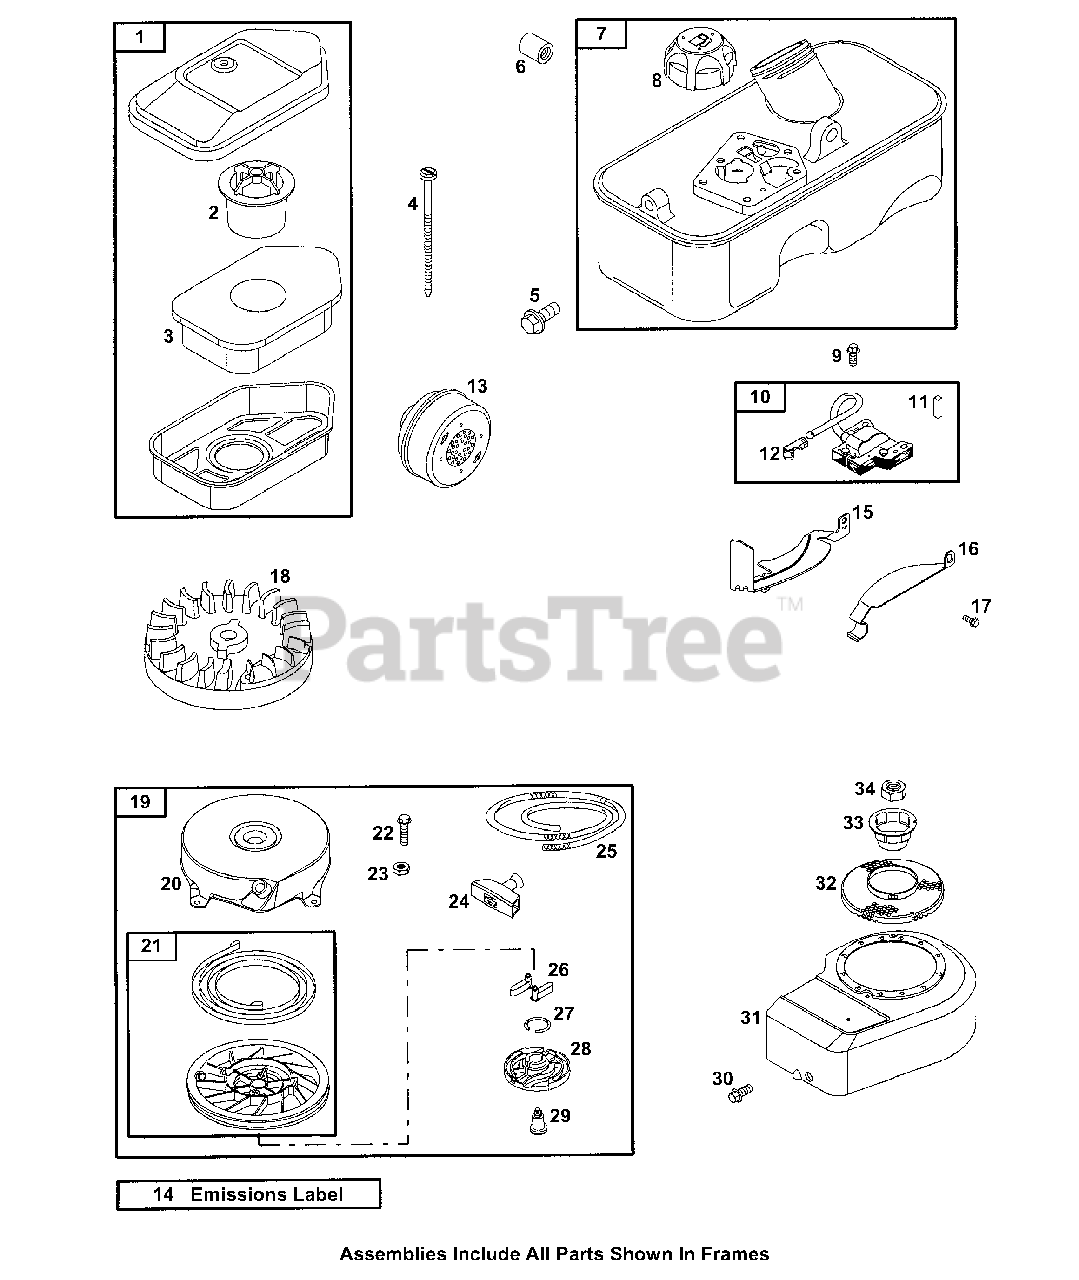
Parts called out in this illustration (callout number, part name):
1	Air Cleaner
2	Foam Element Support
3	Air Cleaner Foam Filter
4	Screw (Air Cleaner)
5	Screw (Fuel Tank)
6	Fuel Tank Spacer
8	Fuel Tank Cap
9	Screw (Magneto Armature)
10	Magneto Armature
11	Flywheel Key
12	Sparkplug Terminal
13	Exhaust Muffler
14	Emissions Label
15	Flywheel Guard (Muffler Side)
16	Flywheel Guard (Carburetor Side)
17	Screw (Flywheel Guard)
19	Rewind Starter
20	Rewind Starter Housing
21	Pulley/Spring Assembly
22	Screw (Rewind Starter)
23	Nut (Rewind Starter)
24	Starter Rope Grip
25	Starter Rope
26	Ratchet Pawl
27	Friction Spring
28	Pawl Friction Plate
29	Screw (Pawl Friction Plate)
30	Screw (Blower Housing)
31	Blower Housing
32	Rotating Screen
33	Flywheel Cup
34	Nut (Flywheel)
